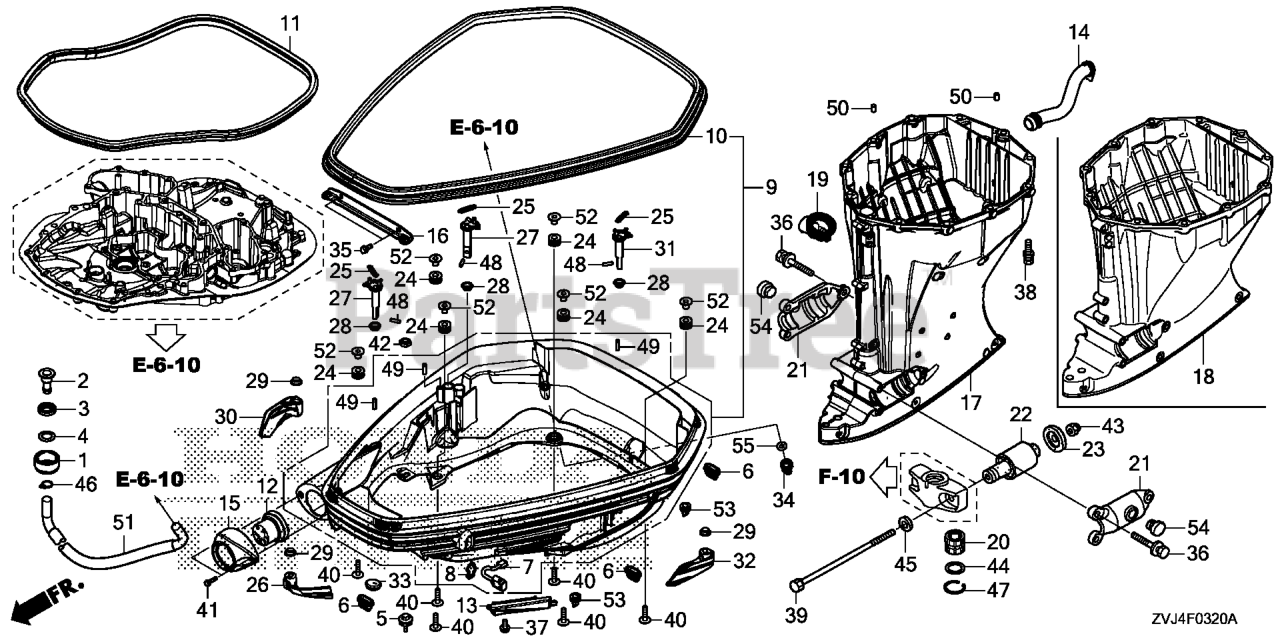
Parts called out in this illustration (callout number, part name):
1	NUT, WATER MOUTH
2	JOINT, WATER HOSE
3	SEAT, WATER MOUTH
4	SEAT, WATER JOINT
5	CAP, WATER JOINT
6	RUBBER, MOUNT CASE SEAL
7	SWITCH ASSY., POWER TILT
8	STAY, POWER TILT SWITCH
9	CASE, ENGINE (LOWER)
10	SEAL A, CASE (LOWER)
11	SEAL B, CASE (LOWER)
12	GROMMET, CASE (LOWER)
13	STAY, HARNESS
14	PORT, IDLE EX.
15	COVER, SEPARATE
16	BRACKET, FR. CASE (LOWER)
17	CASE, EXTENSION (XL)
19	RUBBER, DRAIN PLUG
20	BUSH, VERTICAL SHAFT
21	HOUSING, MOUNTING (LOWER)
22	MOUNT, RUBBER (LOWER)
23	STOPPER, MOUNT (LOWER)
24	RUBBER, FR. CARRIER CUSHION
25	SPRING, LEVER RETURN
26	LEVER, FR. COVER LOCK
27	HOOK, R. COVER LOCK
28	COLLAR A, COVER LOCK
29	COLLAR B, COVER LOCK
30	LEVER, R. COVER LOCK
31	HOOK, L. COVER LOCK
32	LEVER, L. COVER LOCK
33	CAP, L. SIDE COVER
34	GROMMET, WATER CHECK
35	BOLT, FLANGE (8X18)
36	BOLT-WASHER (10X35)
37	BOLT, FLANGE (6X12) Use from Frame SN 1005249.
37	BOLT, FLANGE (6X25)
38	BOLT-WASHER (12X50)
39	BOLT, HEX. (14X180)
40	BOLT-WASHER (8X35)
41	BOLT, FLANGE (6X25)
42	NUT, HEX. (16MM) DUAL QTY = (2) (SINGLE)
43	NUT, SELF-LOCK (14MM)
44	WASHER (30MM)
45	WASHER, PLAIN (14MM)
46	CLIP, TUBE (B12.5)
46	CLIP B1, TUBE
47	CIRCLIP (INNER) (43)
48	PIN, SPRING (6X22)
49	PIN, LOCK SPRING
50	PIN, DOWEL (6X10)
51	TUBE KIT,WATER JO
51	TUBE, WATER JOINT
52	COLLAR (8.5X14.5)
53	GROMMET (1WAY)
54	RUBBER C, STAND STOPPER
55	O-RING (1.9X10)
